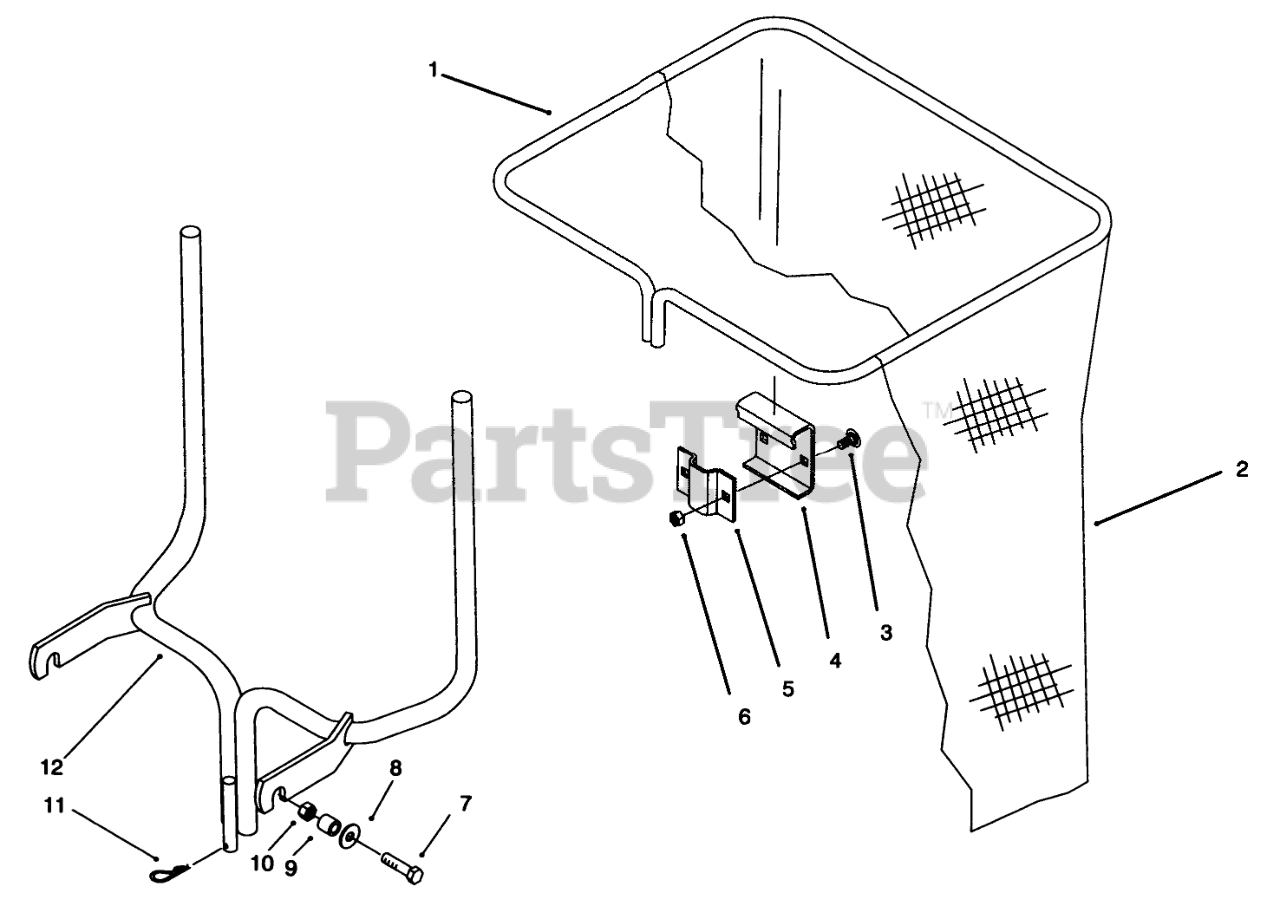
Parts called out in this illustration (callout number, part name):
1	Bag Frame
2	BAG-DEPTH
3	BOLT-CARR
4	Bag Hanger
5	Clamp
6	NUT-LOCK, NI
7	SCREW-HH
8	WASHER
9	SPACER
10	NUT-LOCK, NI
11	Hairpin
12	Bracket-Quick Attach
